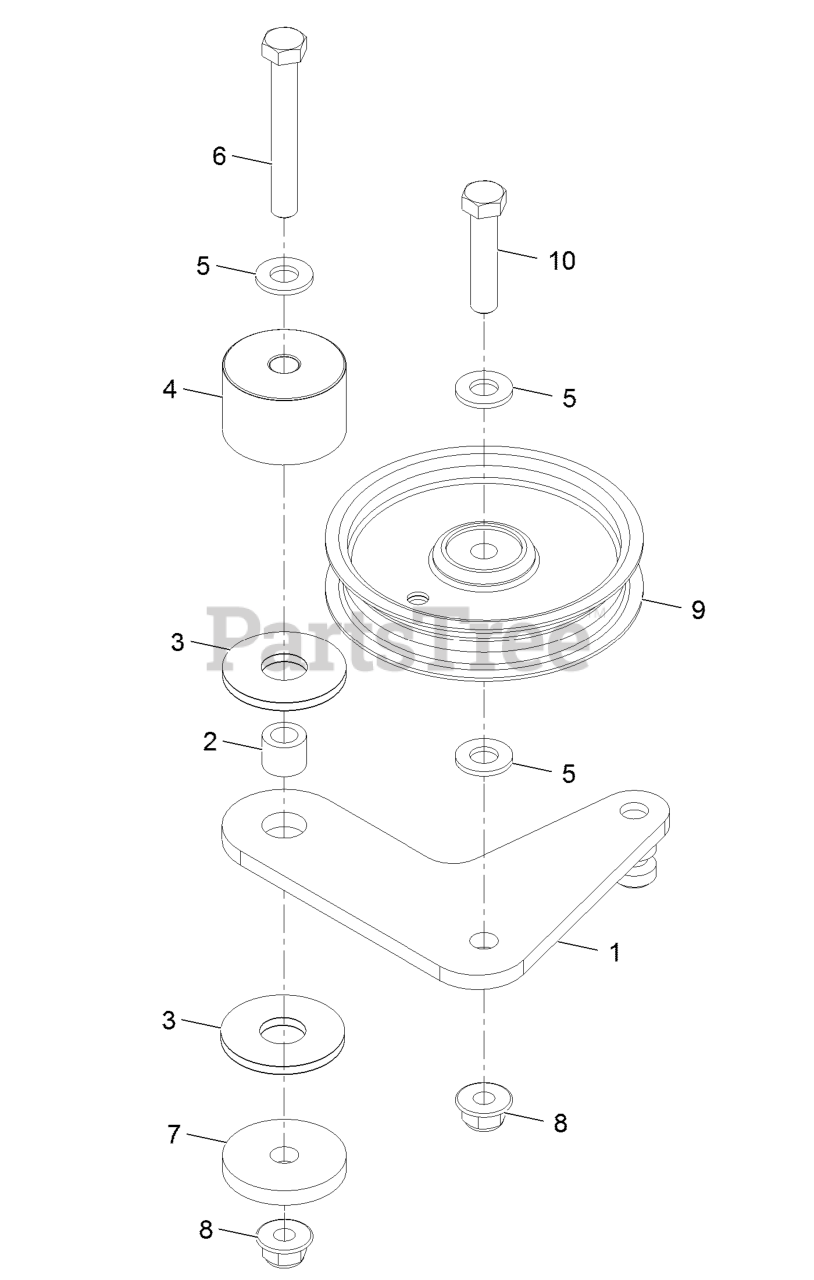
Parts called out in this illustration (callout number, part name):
1	PLATE-IDLER
2	BUSHING-LEVER, LIFT
3	WASHER-FRICTION, COMPOSIT
4	HUB, IDLER
5	WASHER-FLAT
6	SCREW-HH
7	WASHER-PLAIN
8	NUT-HF, NI
9	PULLEY-IDLER
10	SCREW-HH
